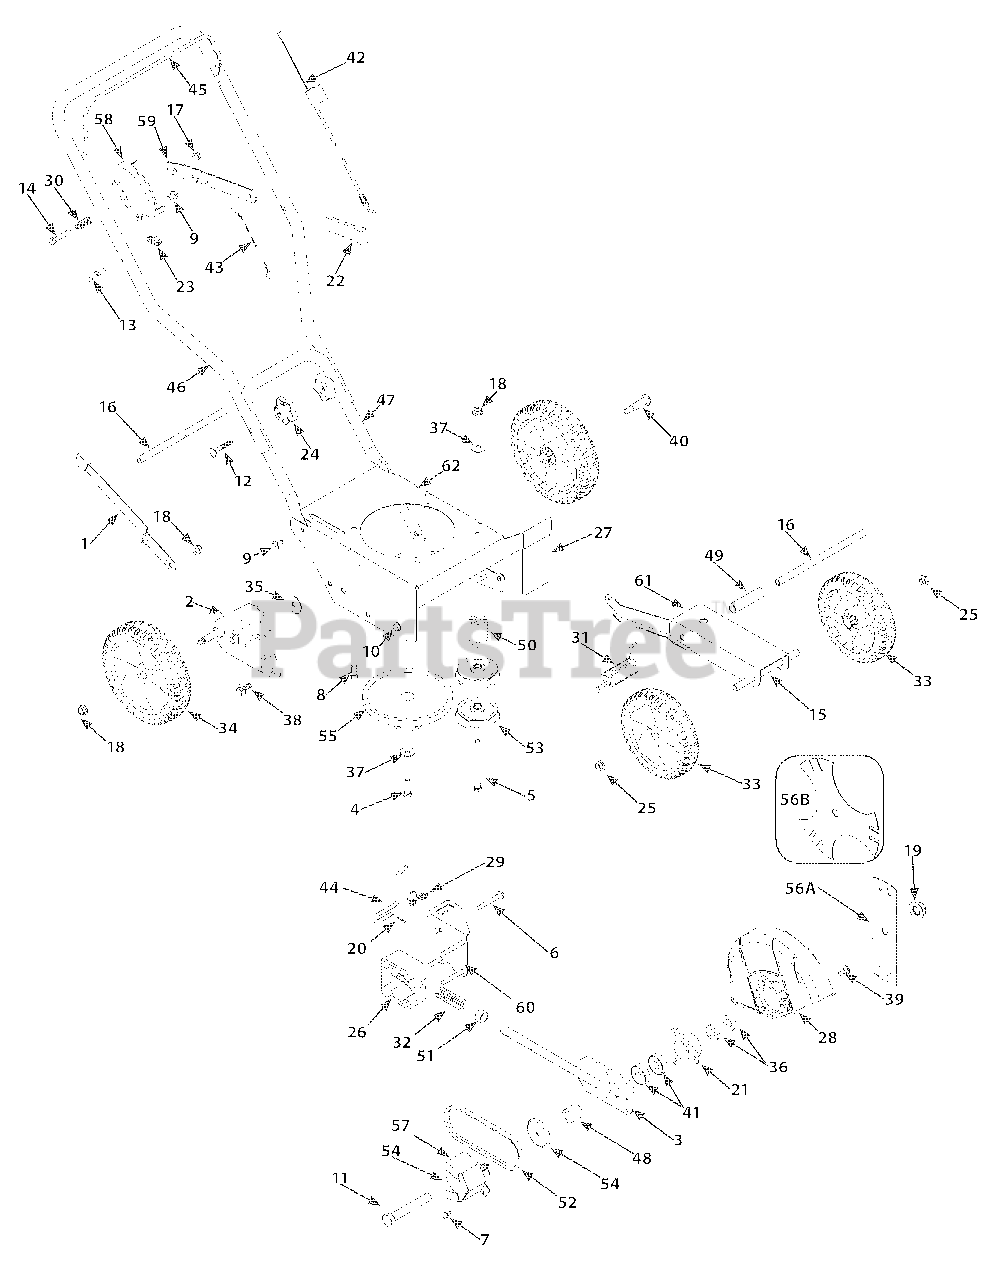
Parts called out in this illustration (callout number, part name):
1	Curb Height Adjustment Lever
2	Curb Height Adjuster Plate
3	Blade Plate Assembly
4	Screw 3/8-24
5	Screw 3/8-16
6	Hex Screw 5/16-18
7	Self Tapping Screw 1/4-20
8	Screw 3/8-16
9	Hex Screw 5/16-12
10	Hex Screw 5/16-18
11	Hex Screw 5/8-18
12	Carriage Bolt, 5/16-18
13	Rope Guide (Eye Bolt)
14	Hex Screw 5/16-18
15	Axle Shaft .50 x 6.65
16	Frame Spacer .50 x 9.25
17	Lock Flange Nut 5/16-18
18	Flange Nut 3/8-16
19	Flange Nut 3/8-18
20	Clevis Pin 3/32 x .625
21	Bearing Cup
23	Wing Nut
24	Star Knob
25	Push Cap 1/2'' Rod
26	Bearing Block
27	Debris Guard
28	Blade Guard
29	Double Torsion Spring
30	Compression Spring
31	Torsion Spring
32	Compression SPring
33	Front Wheel 7 x 1.8 Spoke Bar Grey
34	Rear Wheel 8 x 1.8 Spoke Bar Grey
35	Flat Washer .385 x 1.5 x .075
36	Flat Washer .385 x 1.5 x .075
37	Bell Washer .396 x 1.140
38	Shoulder Screw 3/8-16
39	Shoulder Screw
40	Shoulder Screw 3/8-16
41	Bearing .625 ID x 1.57 OD
42	Control Cable
43	Wheel Adjustment Cable
44	Blade Adjustment Rod
48	Spacer .63 x 1.12 x 1.06
49	Spacer
50	Pulley Mount Spacer
51	Spacer .64 x .88 x .50
52	Belt
53	Flat Idler Pulley 2.5 OD
54	Sheave
55	Combination Flywheel Pulley
